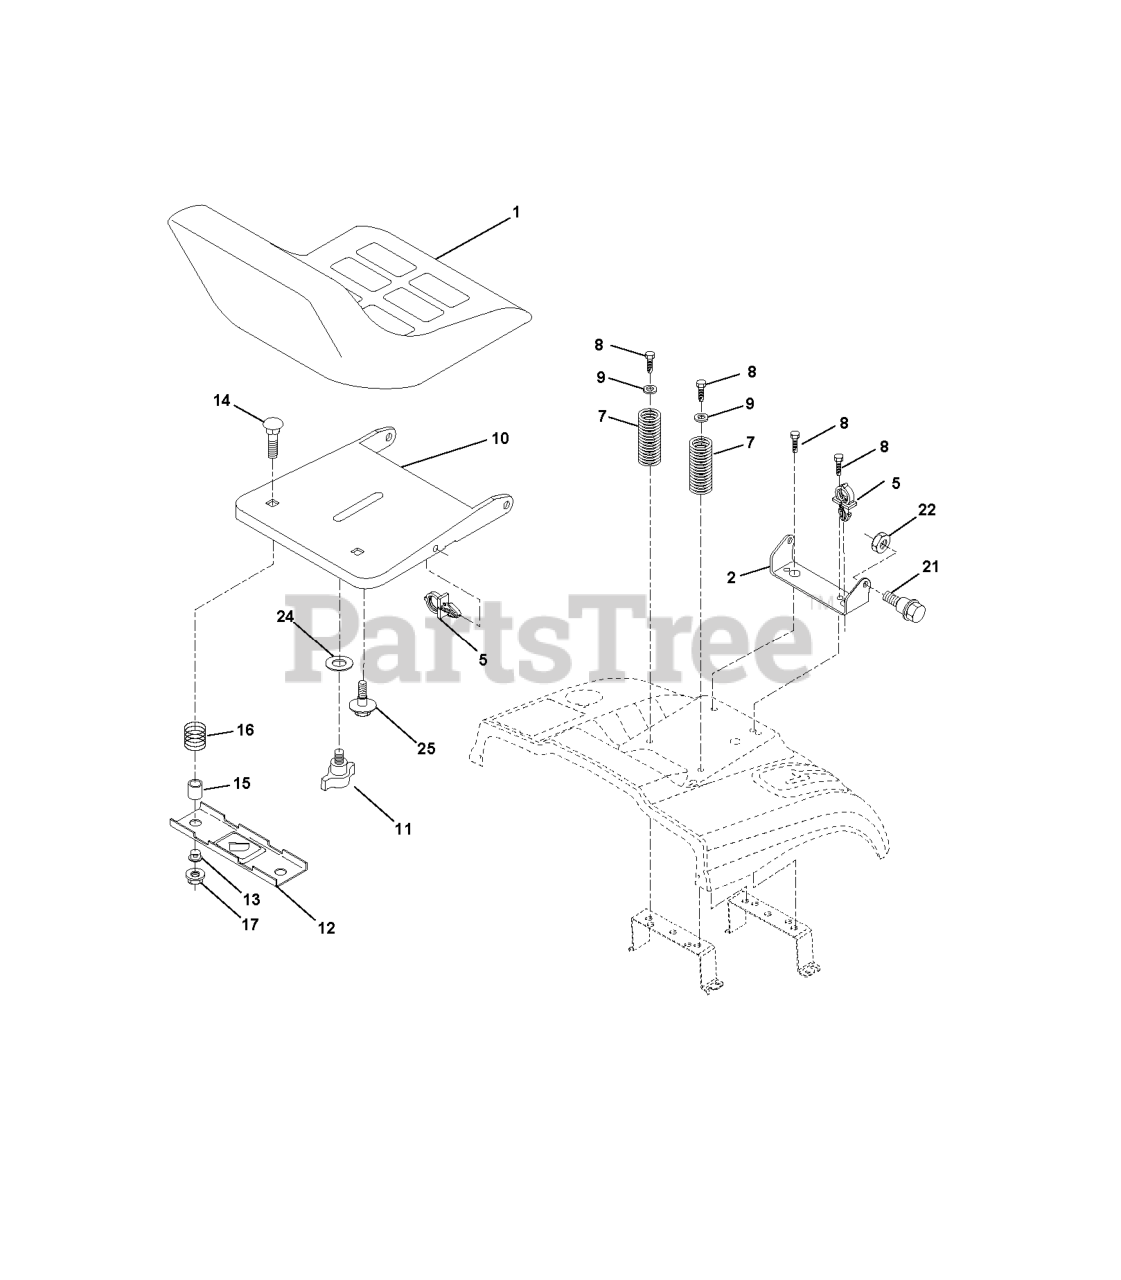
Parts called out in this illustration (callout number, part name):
1	SEAT, GRAY
2	SEAT PIVOT BRKT
7	SPRING COMPRESSION
8	SCREW 3/8-16X1
9	WASHER
10	PAN, SEAT
11	KNOB.SEAT.ADJ.WINGNUT
12	BRKT SWITCH
14	BOLT.ROUND.HEAD.SQUARE.NECK
15	SPACER SPLIT
16	SPRING COMPRESSED
17	NUT T
21	BOLT.SHOULDER.5/16-18
22	NUT.71038.31-18.HEX.NYLOCK
25	BOLT,SHOULD
